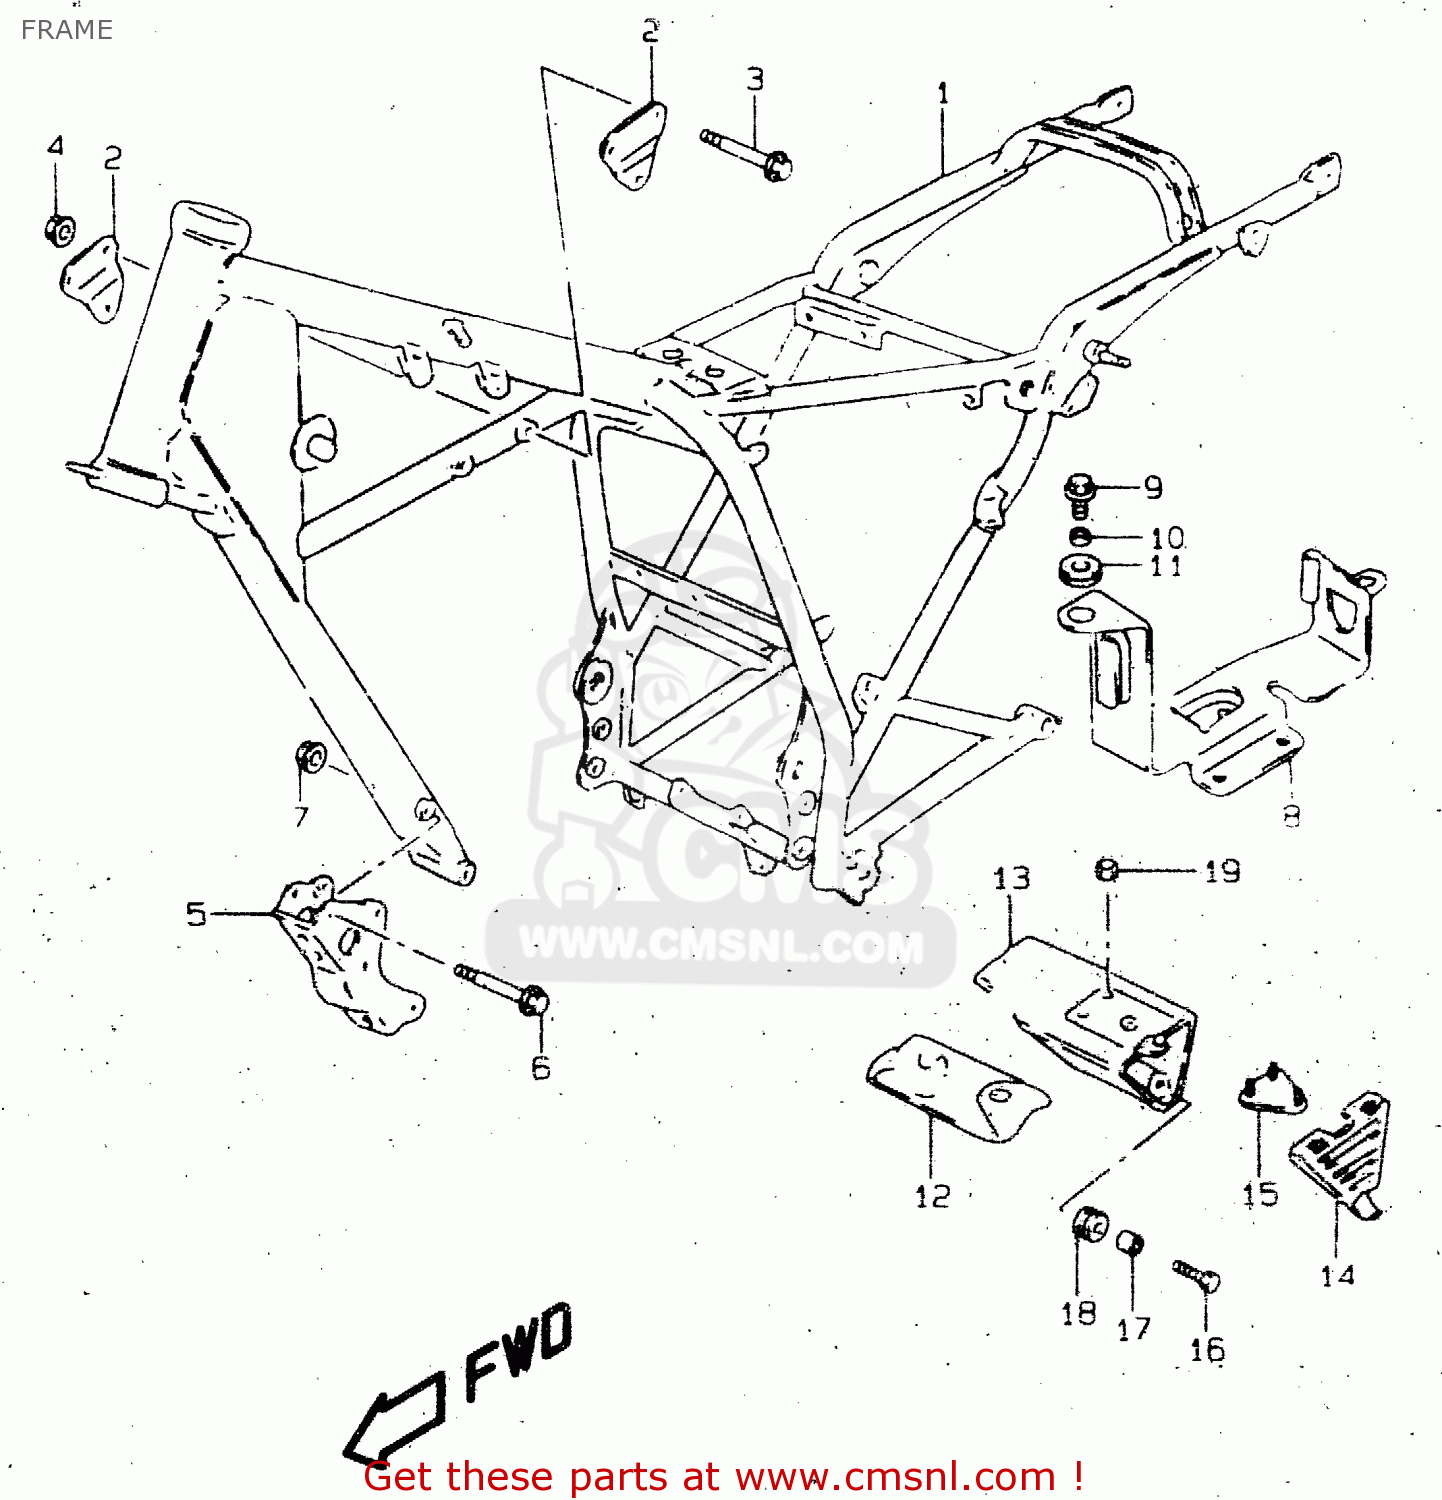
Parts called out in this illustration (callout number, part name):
1	FRAME COMP
2	PLATE,ENGINE MOUNTING
3	BOLT(8X50)
4	NUT
5	BRACKET,ENGINE MOUNTING LWR
6	BOLT
7	NUT
8	HOLDER,BATTERY
9	BOLT(6X16)
10	SPACER(6.1X9X7.5)
11	CUSHION
12	TOOL ASSY
13	BOX,TOOL
14	CAP,TOOL BOX
15	PLATE,TOOL HOLDER
16	BOLT(6X16)
17	SPACER(6.1X9X7.5)
18	CUSHION
19	NUT
